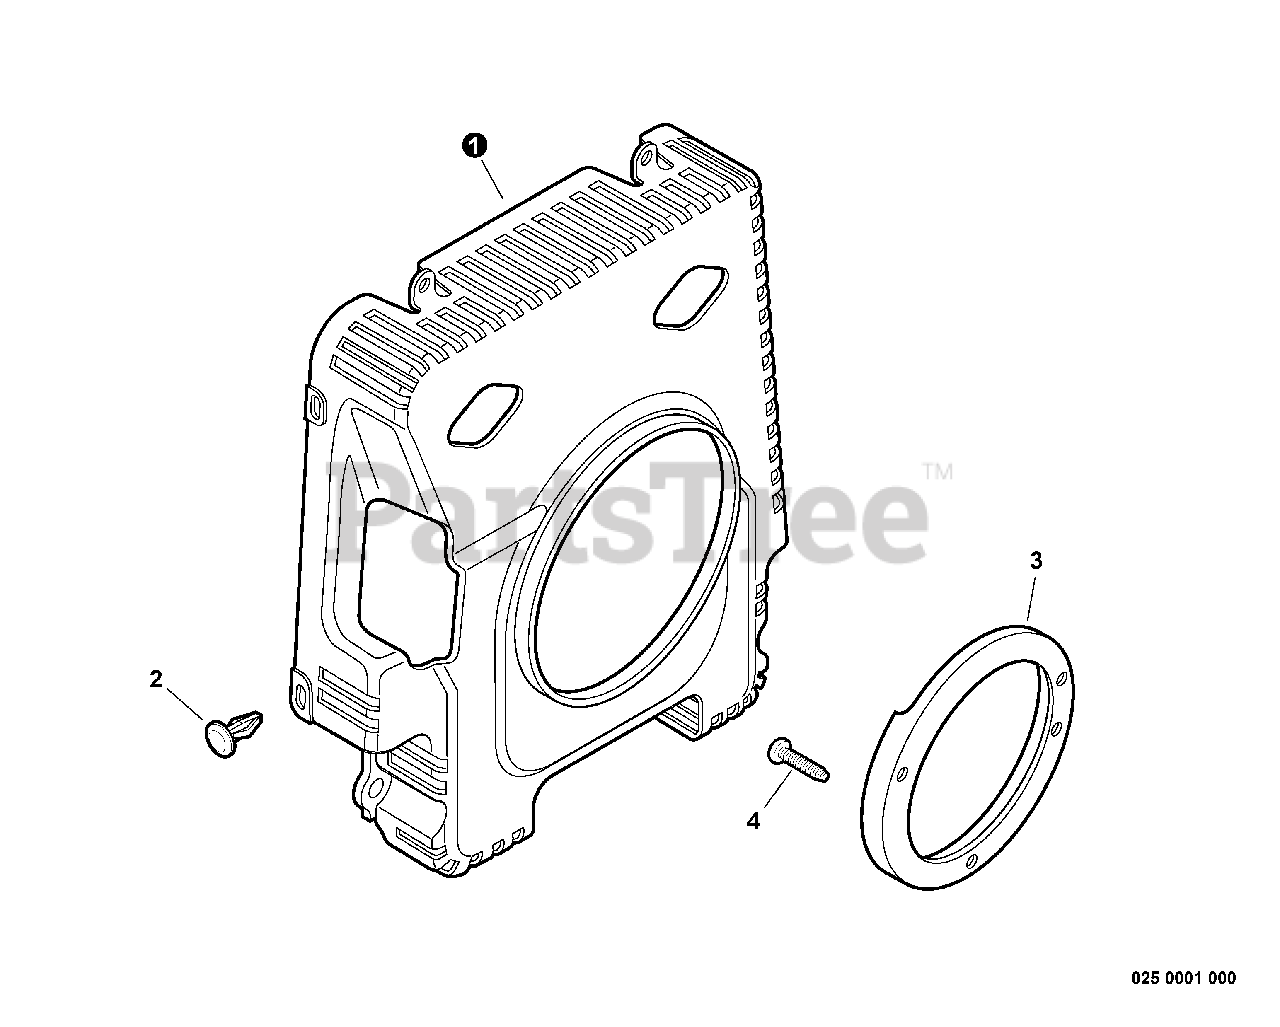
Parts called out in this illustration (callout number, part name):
1	GUARD, DEBRIS
3	DUCT, AIR
4	SCREW 5×16
